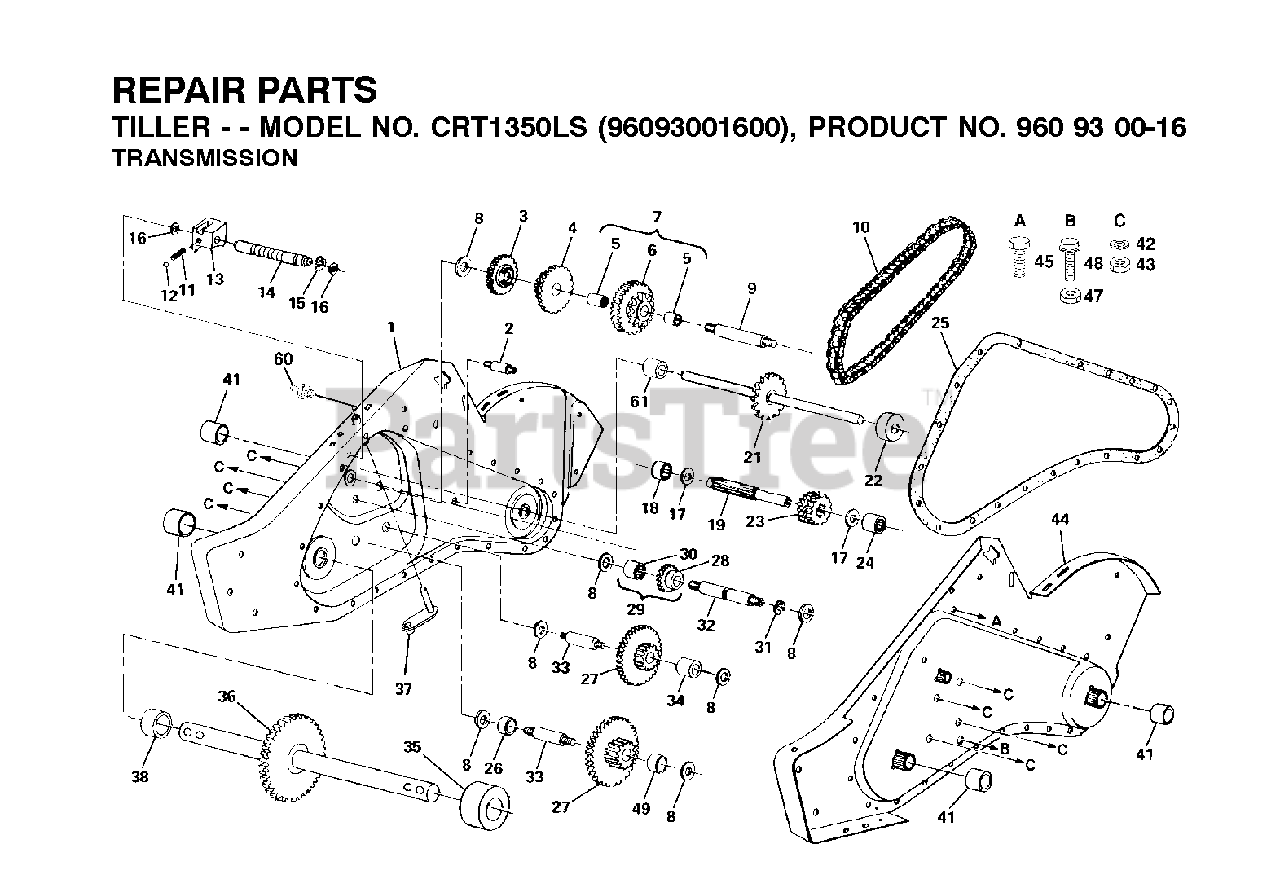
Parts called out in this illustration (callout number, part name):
1	GEARCASE ASM.RH.W/BEARING 2002
2	SPACER.GEARCASE
3	GEAR.REVERSE.8HP
5	BEARING.NEEDLE.CRT
6	SPROCKET ASMBLY, TINE
7	SPROCKET ASMBLY W/BEARINGS
9	SHAFT.REDUCTION.TILLER
10	CHAIN.ROLLER.TILLER
11	SPRING-SHIFT CRT
12	STEEL BALL KIT
13	SHIFT FORK TI
14	SHAFT.SHIFT.1.00 PINION
16	WASHER, SEAL (2 2)
17	THRUST WASHER
18	BEARING TI
19	SHAFT INPUT
21	SHAFT.ASM.TINE.21
22	SPACER 1.008X1-3/4X.645
23	GEAR.PINION
24	NEEDLE BRNG LT
25	GASKET.GEARCASE.8HP
27	GEAR, CLUSTER CRT
28	REVERSE GEAR
29	GEAR ASMBLY, REVERSE IDLER
30	NEEDLE BEARING TI
32	SHAFT, REVERSE IDLER
33	SHAFT, REDUCTION
34	SPACER.765 X 1.12 X .380.
35	SPACER, GROUND DRIVE RH
36	SHAFT ASSY CRT
37	BRACKET ASM.SHIFT.CRT
38	SPACER, GROUND DRIVE
41	SEAL ASM, OIL
42	LOCKWASHER
43	NUT.ASF.HEX.7/16
44	GEARCASE ASM.LH.W/BEARING 2002
45	BOLT.5/16HEX.WHS.HD
48	SCREW 5/16-18X4
60	FITTING.GREASE.TAPERED
61	SPACER.1.015 X 1.50 X .765
